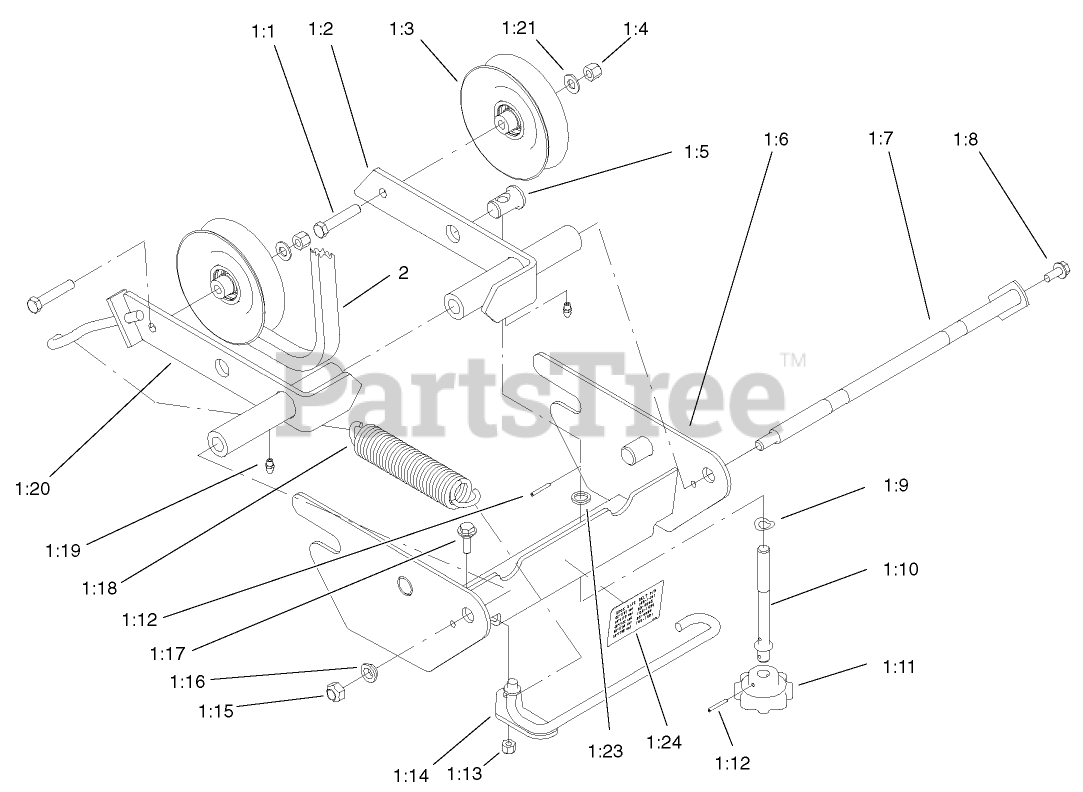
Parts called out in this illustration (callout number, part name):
1	PULLEY BOX ASM
1:1	SCREW-HH
1:2	LH Tension Bracket ASM
1:3	PULLEY-IDLER
1:4	NUT-LOCK, NI
1:5	Ferrule-Adjuster
1:6	Pulley Box ASM
1:7	ROD-PIVOT
1:8	SCREW-HWHTF
1:10	Rod-Tension
1:11	Knob-Adjusting
1:12	PIN-ROLL
1:13	NUT-LOCK, NI
1:14	TENSIONER-IDLER
1:15	NUT-LOCK, NI
1:16	Spacer-Shoulder
1:17	SCREW-SHOULDER
1:18	SPRING-EXTENSION
1:19	FITTING-GREASE
1:20	RH Tension Bracket ASM
1:21	WASHER-PLAIN
1:23	WASHER
1:24	DECAL-PULLEY BOX
2	BELT-V
